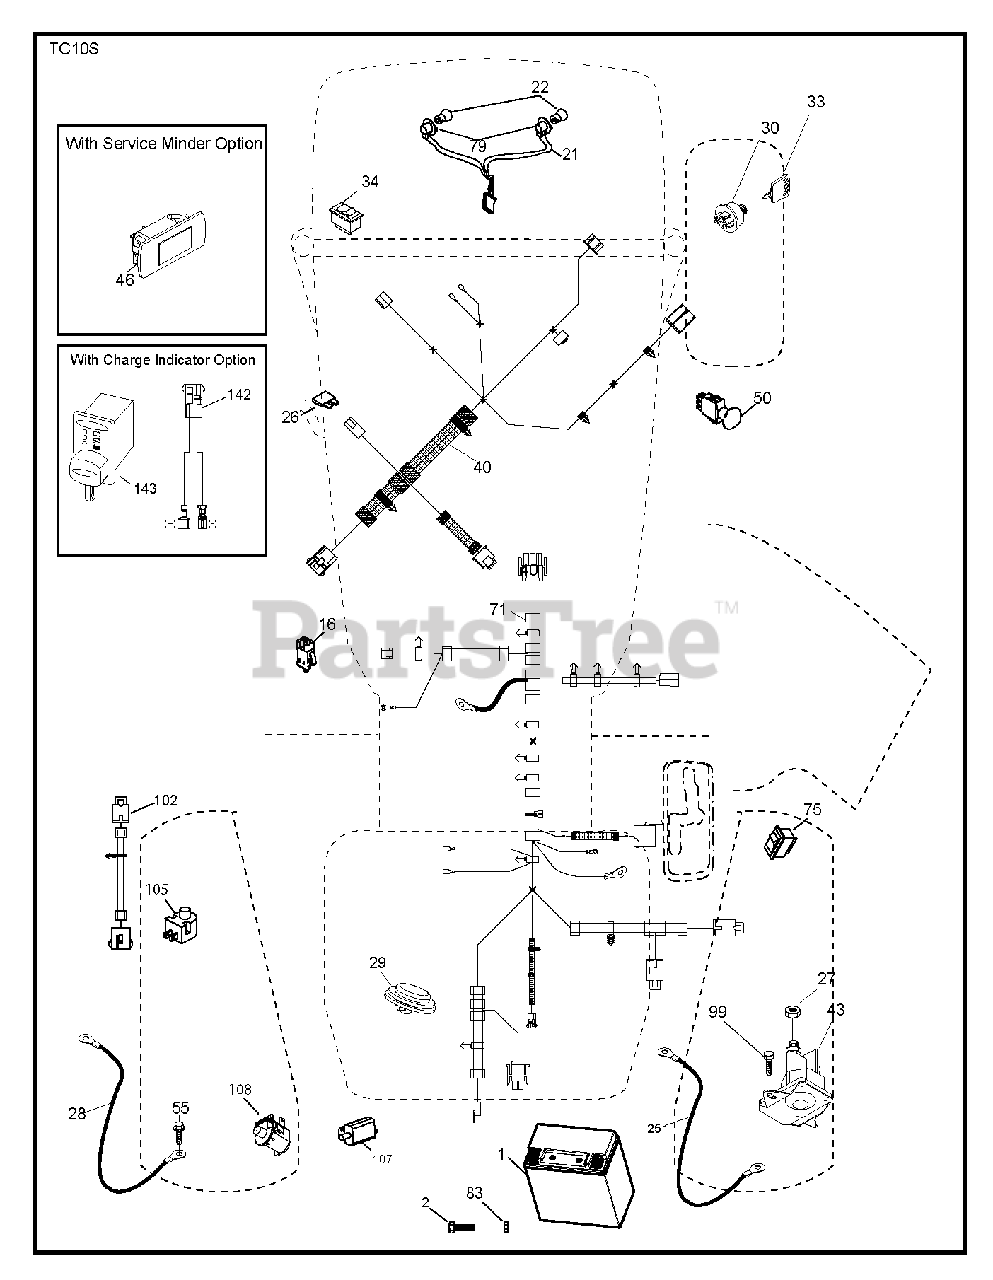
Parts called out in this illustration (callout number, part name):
1	BATTERY BATTERY 14AH 12V LEOC
2	SCREW.HEX.HEAD.CAP.M6 X1.12W
16	SWITCH INTERLOOK PUSH-IN
21	HARNESS.LIGHT W/4152J BULBS
25	CABLE CABLE.RED.20.8AWG.M6.CRD
26	FUSE 20AMP
27	NUT
28	CABLE CABLE.BLACK.20.8AWG.M6.C
29	SWITCH.SEAT.DELTA.OPC.
30	SWITCH.IGN.DELTA.W.LGH.ROS
33	KEY.CHAIN.BLISTER.PACK.GEN.INT
40	HARNESS.DASH.ELECT.SRD.BAT.CHR
43	SOLENOID.W/BRASS.PLUNGER
46	RP GUAGE.SRVCMNDR.HRMTR.
50	RB PTO.SWITCH.8 TERMINAL.BLACK
55	SCREW 5/16"
71	HARNESS.CH.TCRD.HYD.TWIN.ELD.
75	SWITCH.BAG.DUMP
79	BULB HOLDER ASM.
83	NUT NUT SQUARE
99	SCREW
102	HARNESS ASSY
105	REVERSE SWITCH
107	.WITCH.FULL BAGGER.INDICATOR
108	SWITCH.SNAPMOUNT.NC
142	CHARGE.PORT.PIGTAIL HARNESS
143	CHARGE.PORT
